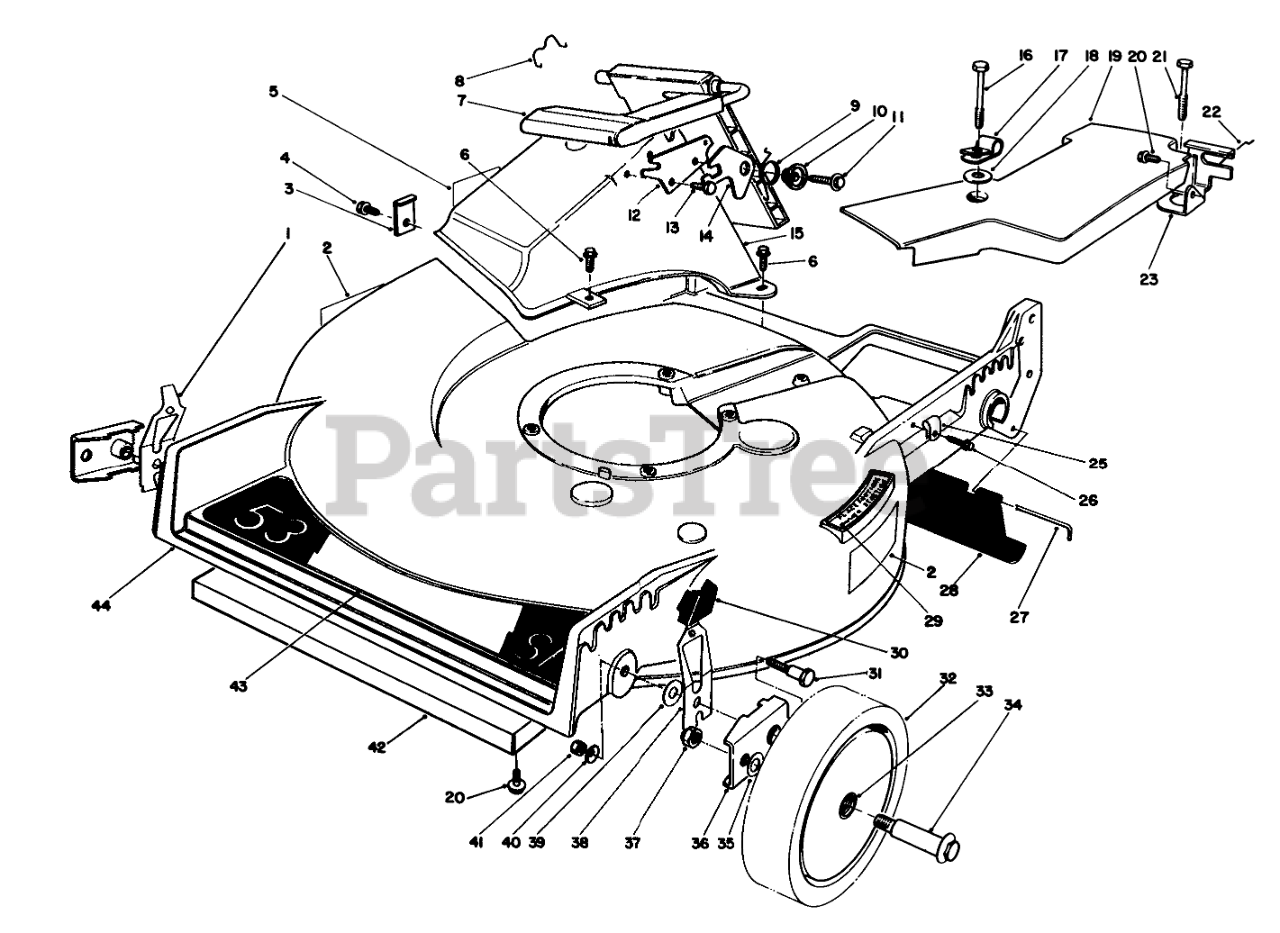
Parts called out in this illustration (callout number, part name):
1	R HP SPRING ARM ASM
2	Decal Danger
3	TUNNEL CLIP
4	SCREW
5	DECAL - DANGER
6	SCREW-HWH
7	Discharge Door Assembly
8	DOOR RET SPRING
9	TORSION SPRING
10	DOOR SPACER
11	SCREW-HWH
12	DOOR LATCH PLATE
13	SCREW-PLASTITE
14	SAFETY LATCH
15	Tunnel Discharge
16	SCREW-SPECIAL
17	CLAMP-CABLE
18	WASHER
19	Belt Cover
20	SCREW-HWHTF
21	SCREW-HHFTF
22	RETAINER-CABLE
23	Bracket-Traction Adj.
25	CLAMP-CABLE
26	SCREW
27	ROD-SHIELD
28	SHIELD-TRAILING
29	Decal-Step Pad
30	KNOB-ARM
31	PIVOT SCREW
32	Wheel & Tire Assembly (Incl. Ref. #33)
33	BUSHING
34	WHEEL BOLT
35	WASHER
36	HP PIVOT ARM ASM
37	Nut
38	L. HP SPRING ARM ASM
39	WASHER-PIVOT
40	WASHER-BELLEVILLE
41	NUT-LOCK, NI
42	Shield-front
43	DECAL - 53 SP DECK
44	21" Housing
